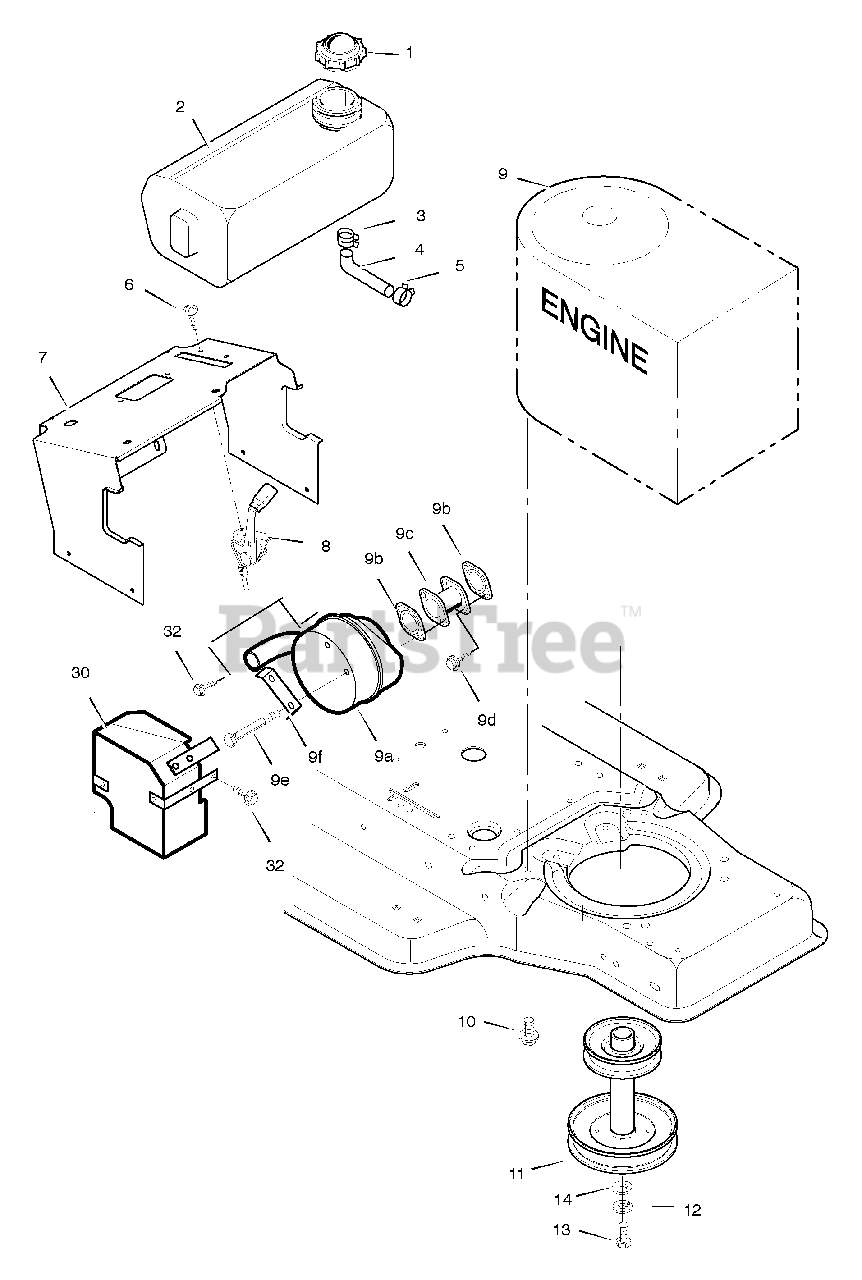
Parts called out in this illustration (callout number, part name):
1	Fuel Cap
2	Fuel Tank
3	Hose Clamp
4	Fuel Line (Must cut to length)
5	Hose Clamp
8	Throttle Control
9	Engine *
10	Bolt, Engine Mount
11	Stack Pulley Assembly
12	Lockwasher
13	Bolt, Hex
30	Shield, Heat
